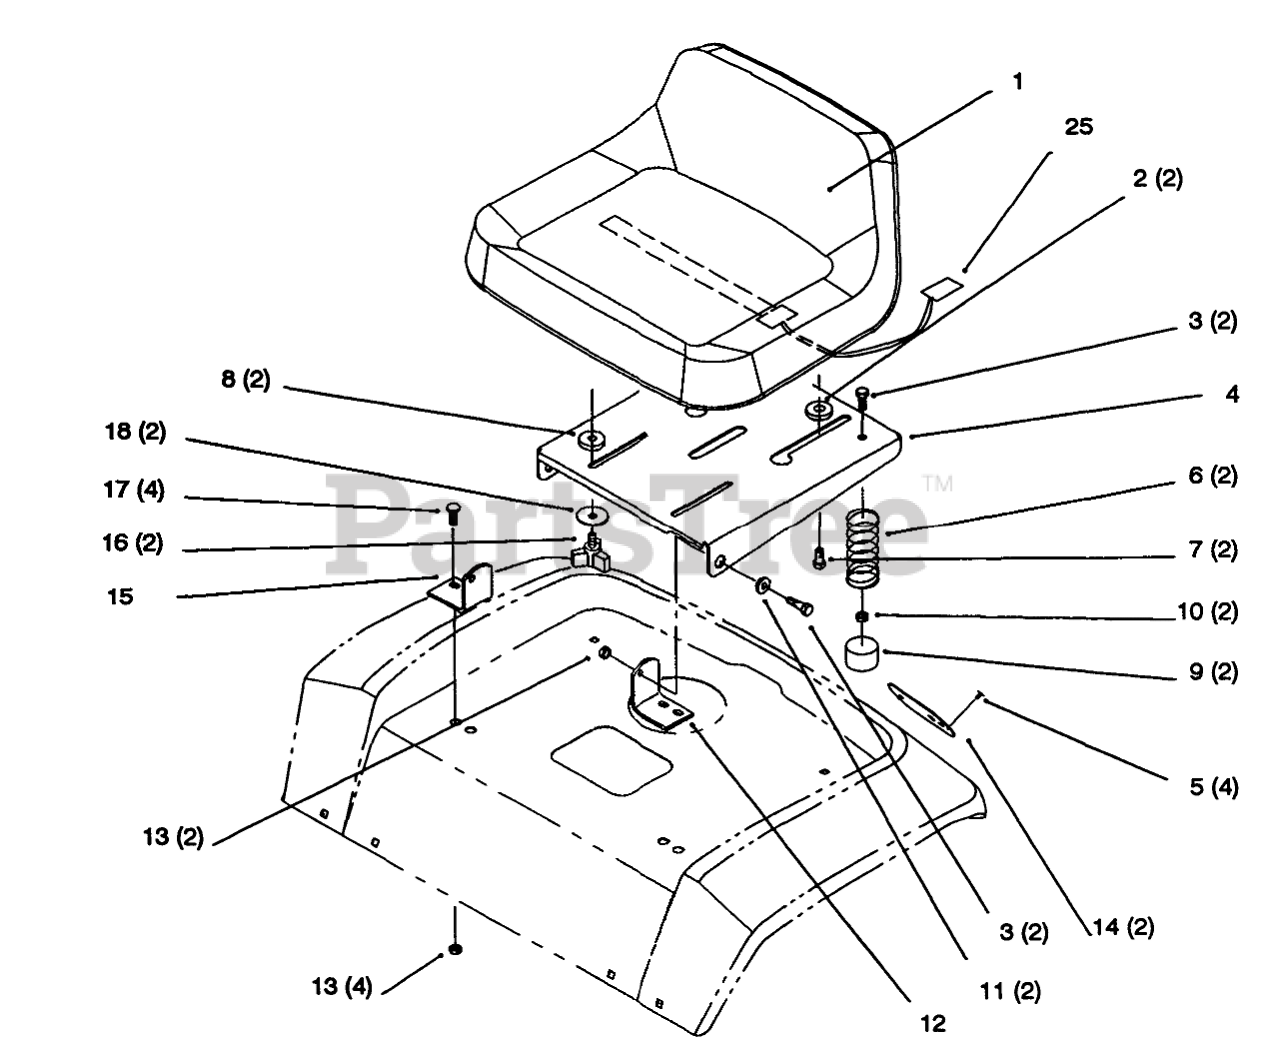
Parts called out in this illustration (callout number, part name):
1	Seat (Only On: 72042, 72043)
1	Seat (Only On: 72062, 72063, 72083, 72103)
2	SPACER-NYLON
3	SCREW-HH
4	SUPPORT - SEAT (BLACK)
5	RIVET-BLIND
6	SPRING-COMPRESSION
7	BOLT-SHOULDER
8	SPACER-NYLON
9	CAP-PROTECTOR
10	NUT-LOCK, NI
11	BUSHING
12	BRACKET-PIVOT, LH
13	NUT-LOCK, NI
14	REFLECTOR-STICK ON
15	BRACKET-PIVOT, RH
17	BOLT-CARR
18	WASHER-PIVOT
25	SWITCH-SEAT
